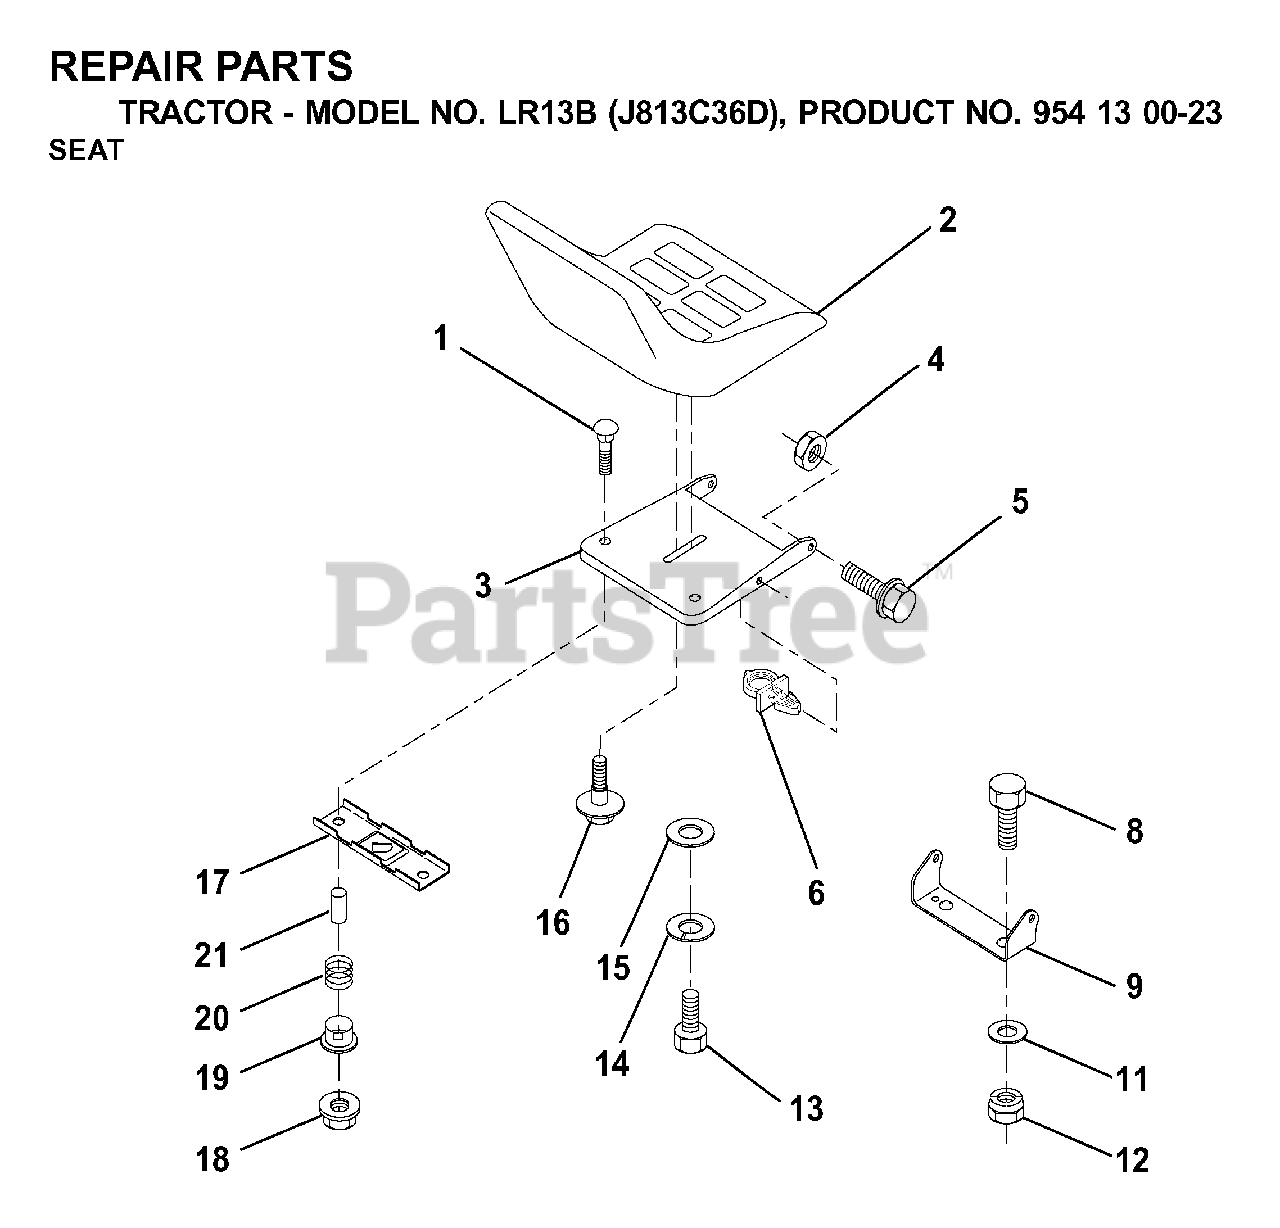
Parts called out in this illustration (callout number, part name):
1	BOLT.ROUND.HEAD.SQUARE.NECK
2	SEAT
3	PAN, SEAT
4	NUT.71038.31-18.HEX.NYLOCK
5	BOLT SHOULDER 5/16-18
6	BOLT.SHOULDER.5/16-18
8	BOLT
9	SEAT PIVOT BRKT
11	WASHER 12/32X2X10GA
12	NUT
13	BOLT.HEX.BLACK
14	LOCKWASHER
16	BOLT,SHOULD
17	BRKT SWITCH
18	NUT T
21	SPACER SPLIT 28X.96
